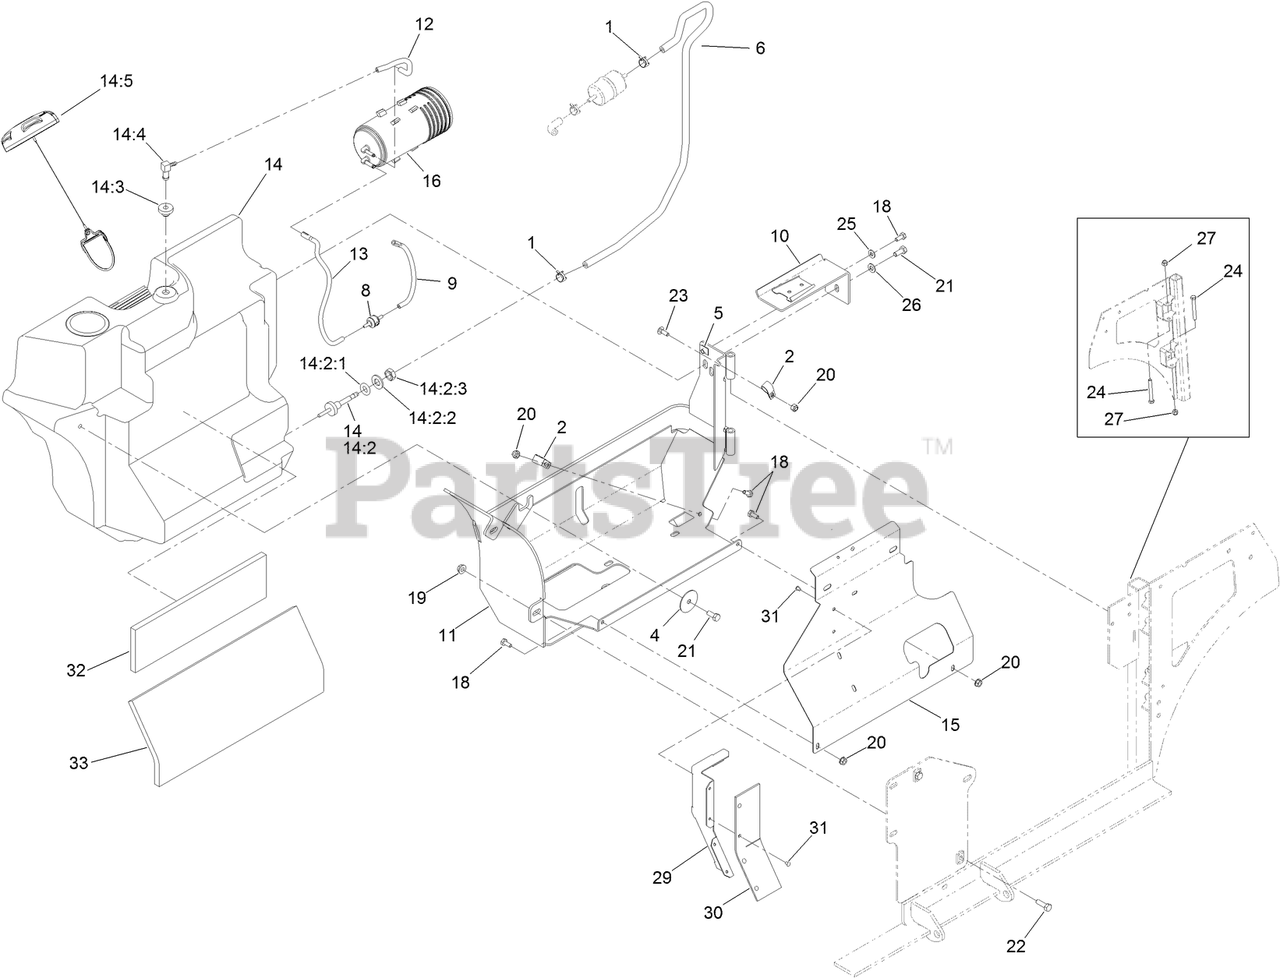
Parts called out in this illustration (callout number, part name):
1	CLAMP-HOSE
2	CLIP-LOOM
4	WASHER
6	FUEL LINE ASM
8	VALVE-CHECK, VACUUM
9	HOSE-VENT, FORMED
10	CANISTER BRACKET ASM
11	TANK FRAME ASM
12	HOSE-VENT, FORMED
13	HOSE-VENT, FORMED
14	FUEL TANK ASM
14:2	FITTING-FUEL, BULKHEAD
14:2:1	O-Ring
14:2:2	WASHER-FLAT
14:2:3	NUT-JAM
14:3	BUSHING
14:4	FITTING-90 DEG
14:5	CAP-FUEL, RATCHETING
15	PANEL-TANK SHIELD
16	CANISTER-CARBON, 800CC
18	SCREW-HH
19	NUT-HF
20	NUT-HF
21	SCREW-HH
22	SCREW-HH
23	BOLT-CARR
24	SCREW-HH
25	WASHER-FLAT
26	WASHER-PLAIN
27	NUT-LOCK, NI
29	DEFLECTOR-AIR
30	FLAP-RUBBER
31	RIVET-POP
32	INSULATION-FOAM PAD, FRONT
33	INSULATION-FOAM PAD, REAR
